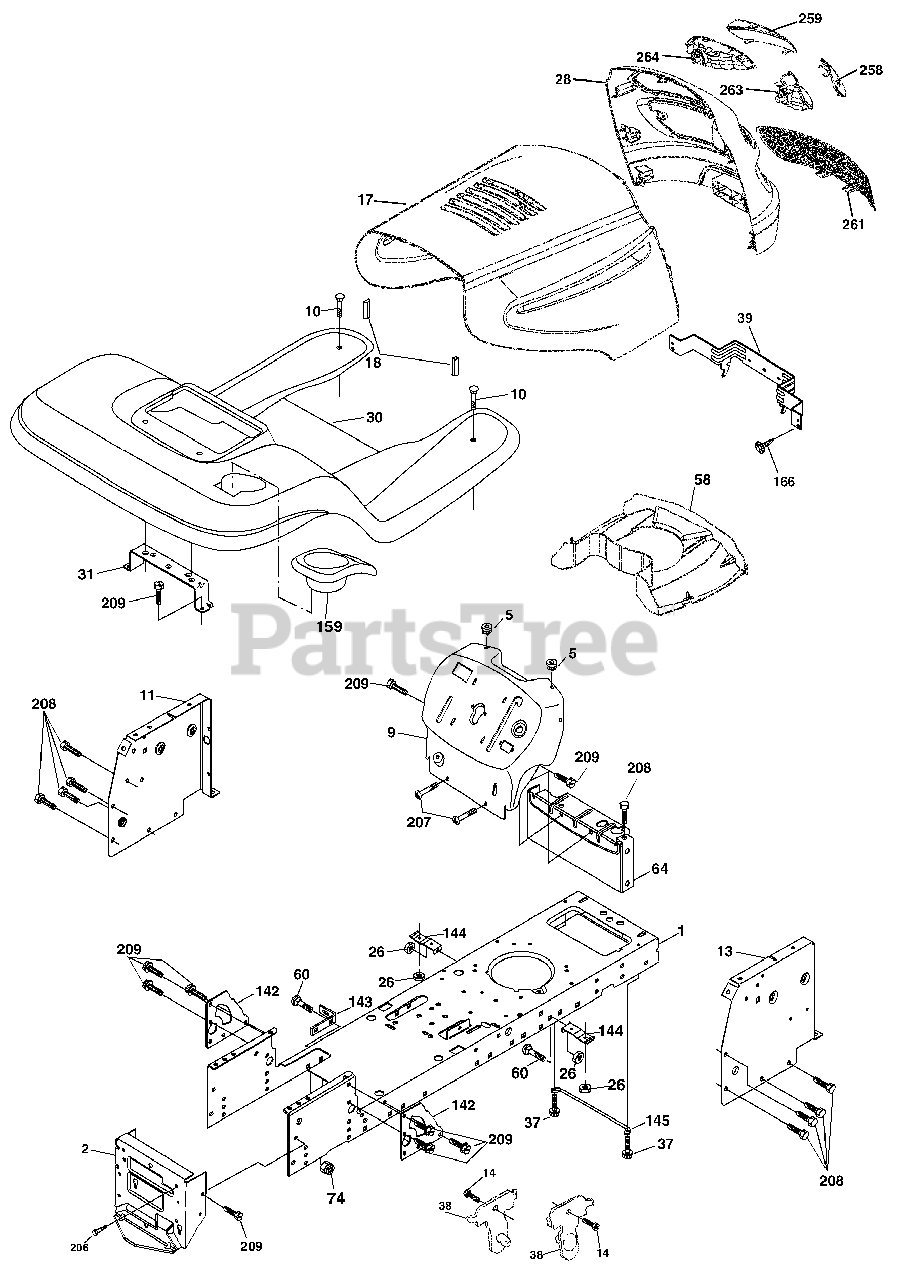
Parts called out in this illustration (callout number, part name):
1	Chassis
2	Drawbar
5	Bumper Hood/Dash
10	Bolt, Carriage 3/8-16 x 3/4
11	Panel, Dash, L.H.
13	Panel, Dash, R.H.
14	Screw Thdrol 3/8-16 x 1/2
17	Hood
18	Bumper Hood
26	Nut
28	Grille/Lens Asm.
31	Bracket, Fender Support
37	Screw Thdrol 5/16-18 x 1/2
38	Pivot Bracket Assembly, Rear
39	Bracket Pivot Laser Lt
58	Duct Intake
60	Bolt Rdhd Sqnk 3/8-16 UNC x 1
64	Dash Lower STLT
74	Nut Crownlock 3/8-16 UNC
142	Plate Reinforcement STLT
143	Bracket Swaybar Chassis
144	Bracket Pnt Footrest STLT
145	Rod Pivot Chassis/Hood
159	Cupholder Stlt Black
166	Screw 10 x 3/4 Single Lead-Hex
206	Bolt Shoulder 5/16-18 TT
207	Screw Thdrol 5/16-18 x 1/2 Tytt
208	Screw Thdrol 3/8-16 x 1/2
209	Screw Hexwsh Thdr. 3/8-16 x 3/4
258	Lens RH
259	Lens LH
263	Bezel RH
264	Bezel LH
